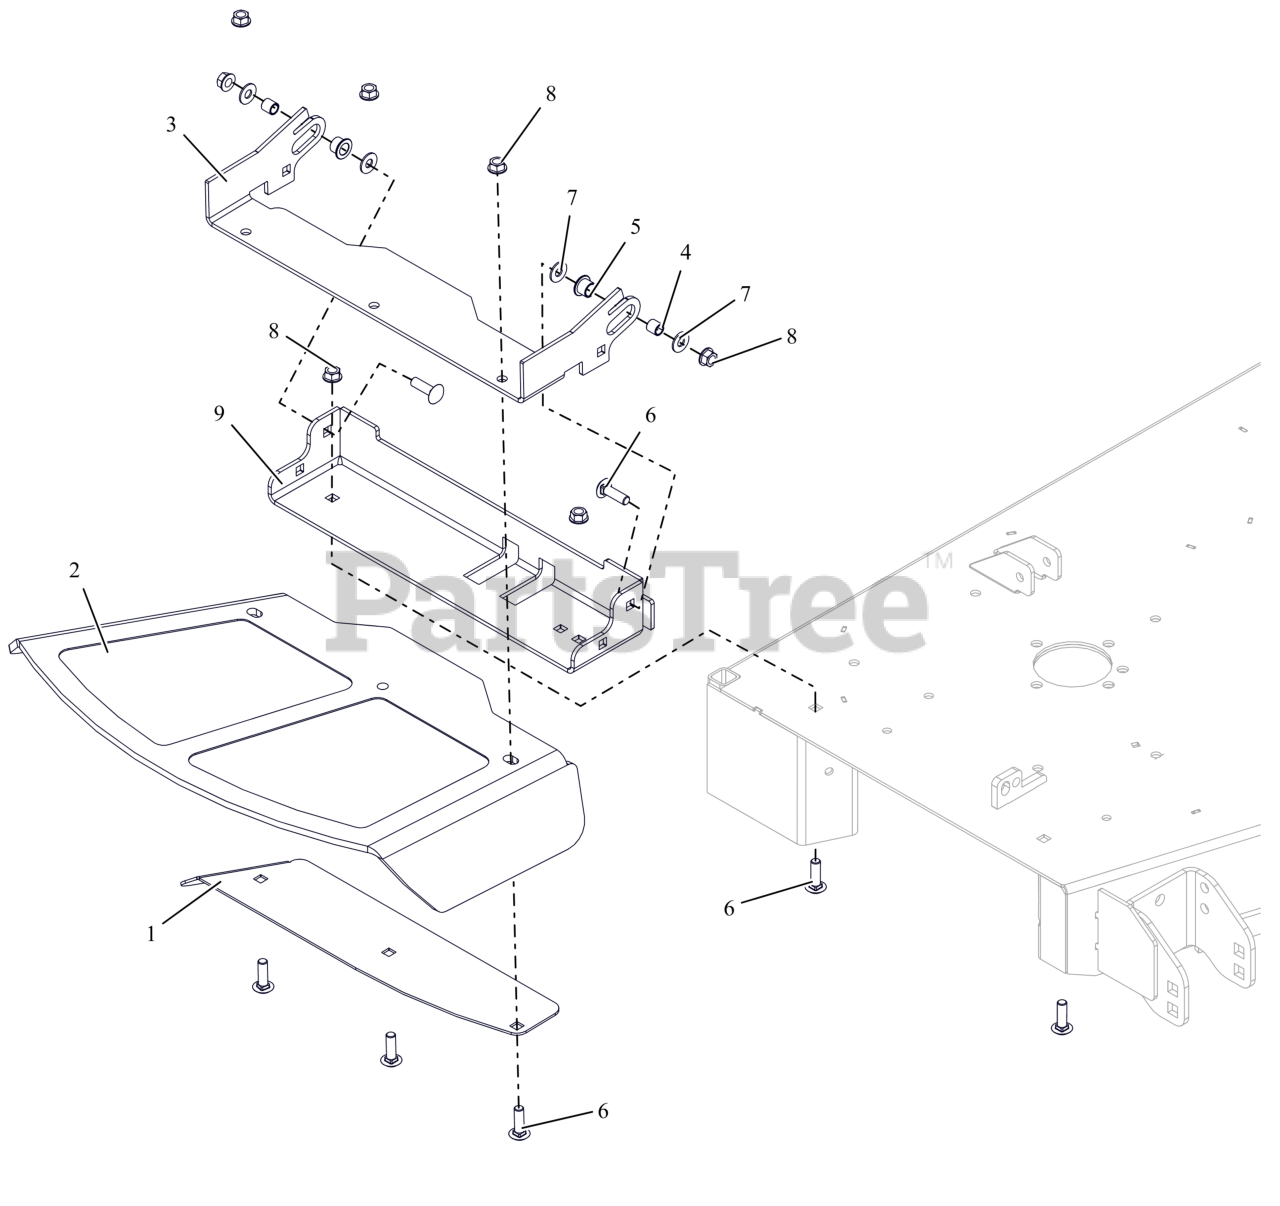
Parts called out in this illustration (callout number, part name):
1	48-60 DISCH CHUTE CLMP PLT-RED
2	CHUTE, FORMED RUBBER DISCHARGE
3	BRKT, CHUTE MOUNT (RED)
4	SPCR, .385X.500X.350
5	BSHG, FLANGED .50X.625X.50X.062
6	BLT,RHSSN .38-16X1.25 G5 ZCC
7	WSHR, HDND 0.375X0.875X0.064 ZCC
8	NUT-LK-CTR-FLG .375-16 GF ZCC
9	BASE, DISCHARGE CHUTE MTG BRKT (RED)
